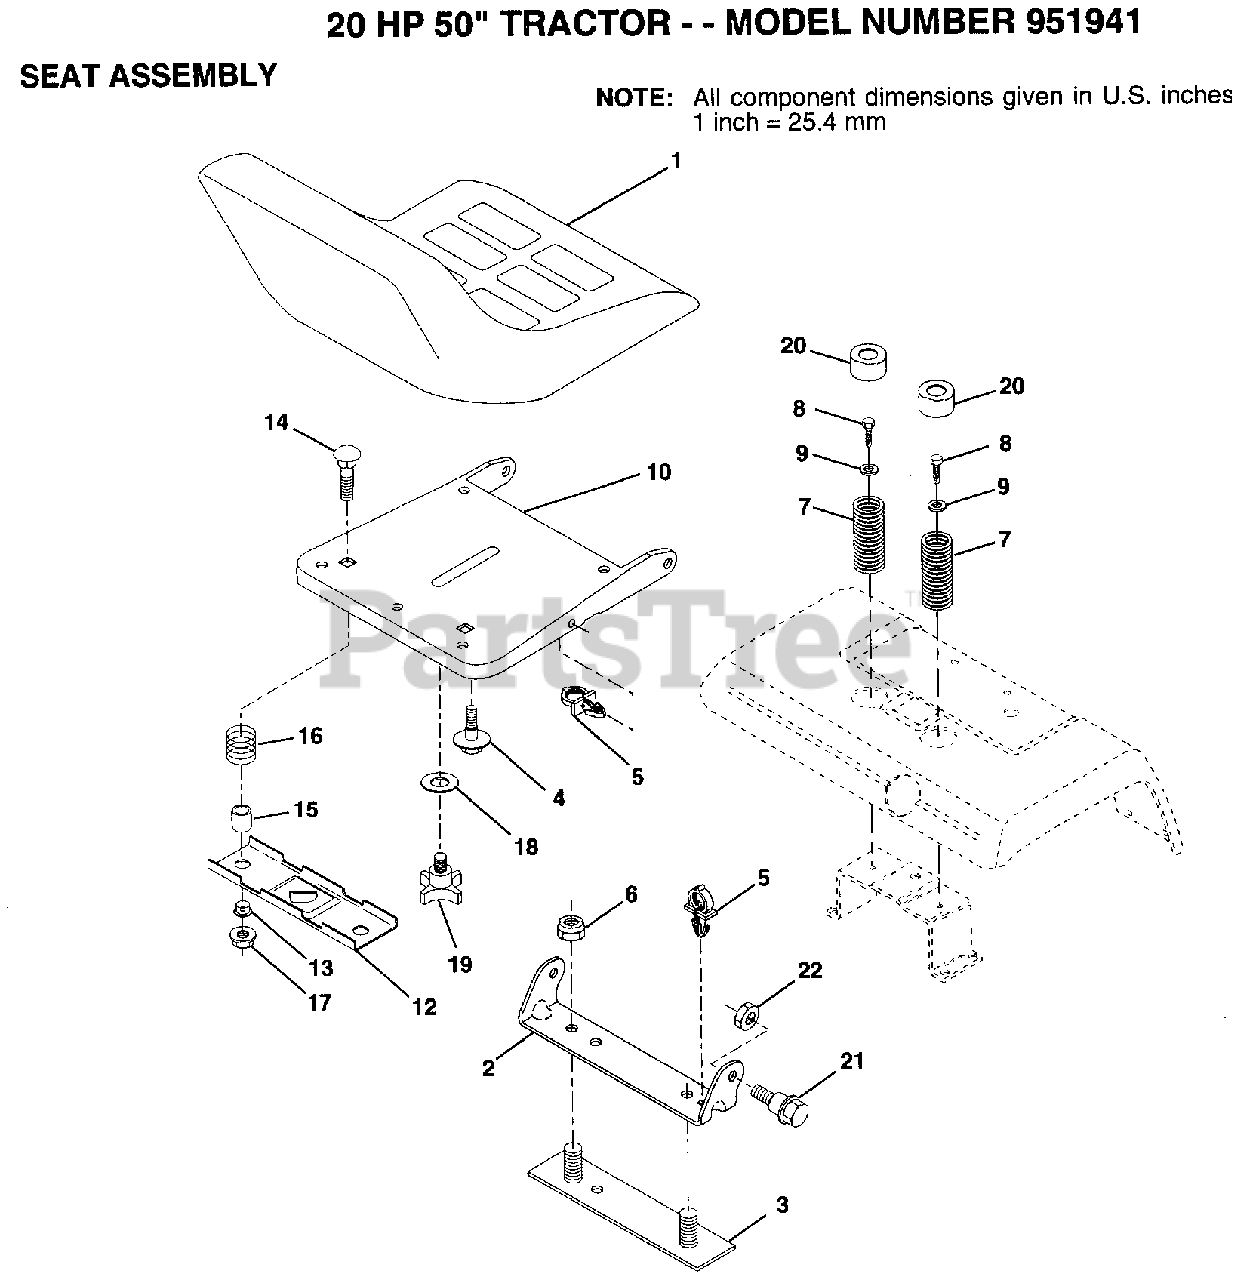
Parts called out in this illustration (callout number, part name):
2	BRACKET PVT SEAT
3	STRAP ASM FENDER
4	"BOLT,SHOULDER"
5	CLIP PUSH - IN
6	NUT
7	SPRING COMPRESSIO
8	SCREW LT
9	WASHER
12	BRKT SWITCH
13	BUSHING
15	SPACER SPLIT
16	SPRING COMPRESSED
18	WASHER
19	"KNOB 1/2"" YT"
20	CAP SPRING
21	BOLT.SHLD.5/16-18
